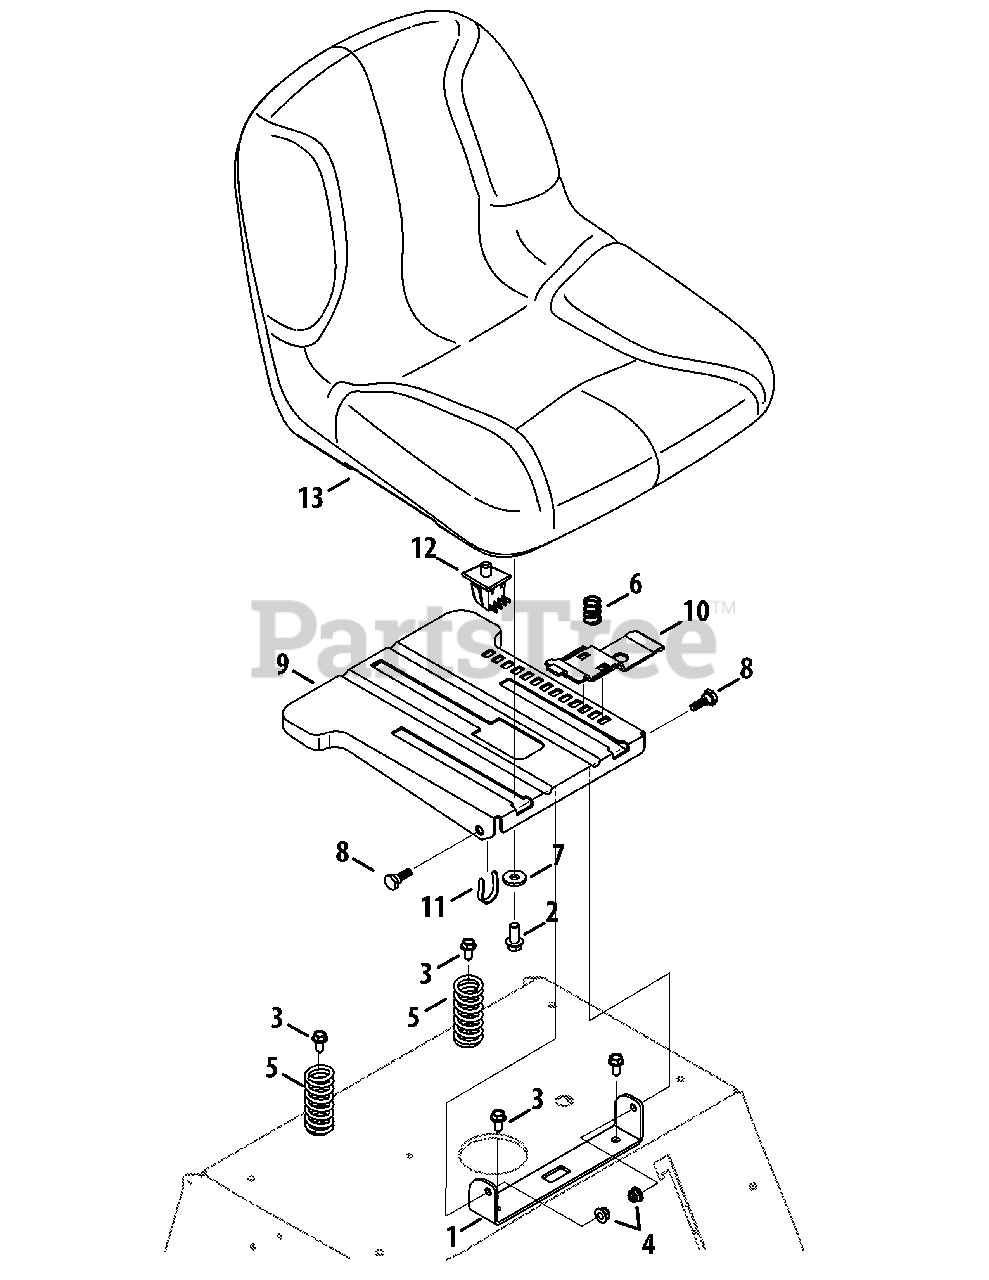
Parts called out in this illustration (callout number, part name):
1	Seat Bracket
2	Hex Flange Bolt, 3/8-16 x .875
3	Hex Washer Screw, 5/16-18 x .750
4	Flange Lock Nut, 5/16-18
5	Compression Spring, 1.50 x 3.90 x .200
6	Compression Spring, .68 x 1.065 x .055
7	Flat Washer, .385 x 1.0 x .135
8	Shoulder Screw, .437 x .268 x 5/16-18
9	Seat Mount Bracket
10	Seat Adjustment Lever
12	Seat Switch
13	High Back Seat
